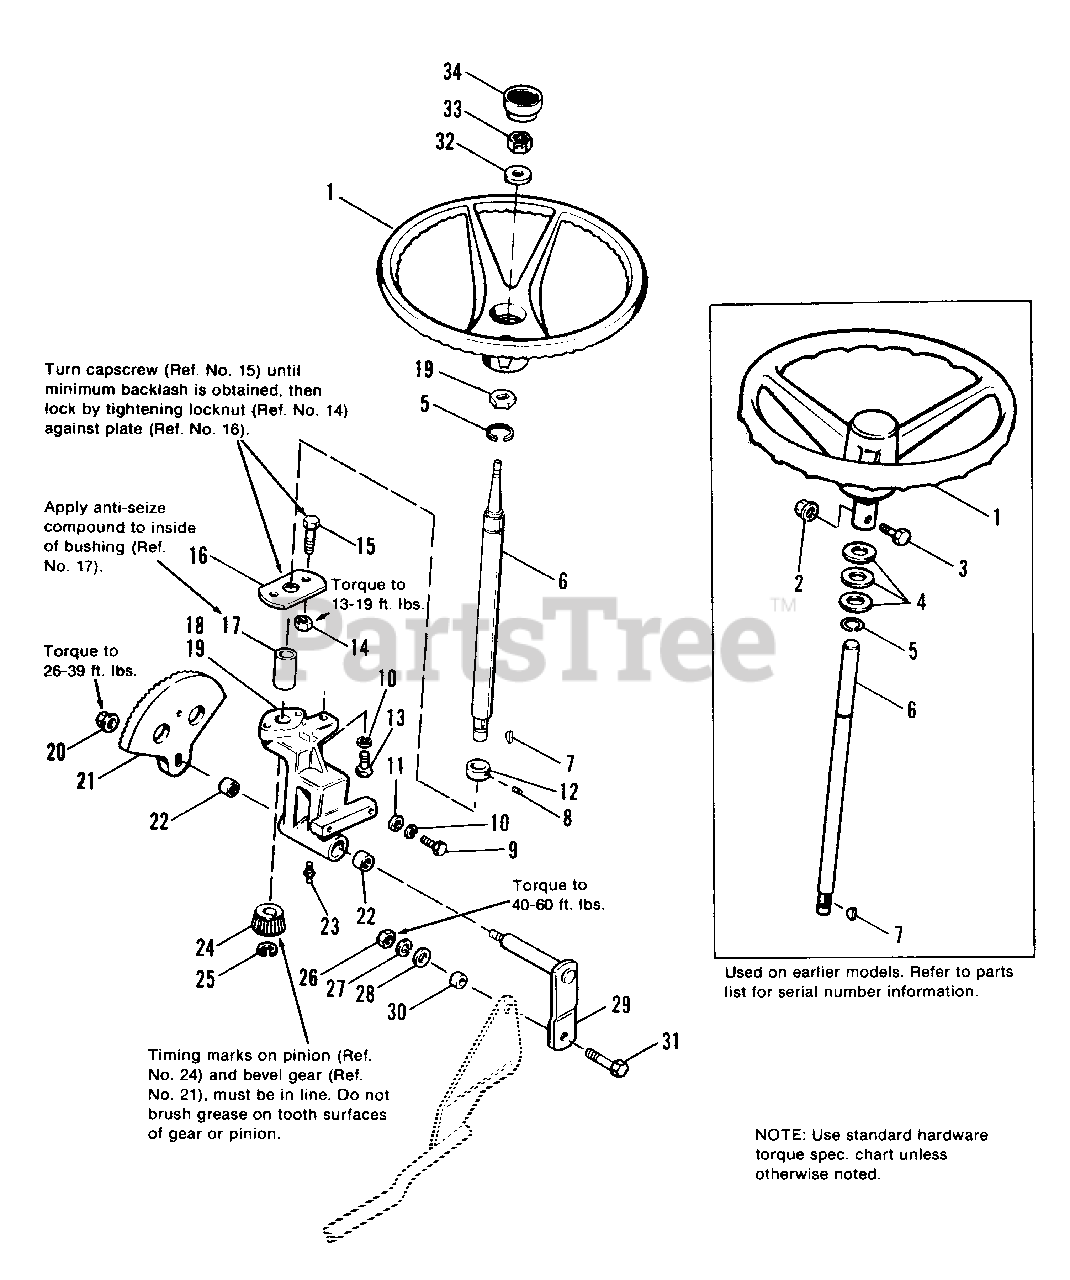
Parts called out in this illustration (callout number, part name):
1	WHEEL, Steering
2	LOCKNUT, Hex, Flange, 5/16-18
3	CAPSCREW, Hex Hd., 5/16-18 x 1-1/4
4	WASHER
5	RING, Retaining
6	SHAFT, Steering
7	KEY, Woodruff, #6
8	SETSCREW, 5/16-18 x 1/4
9	CAPSCREW, Hex Hd., 3/8-16 x 7/8
10	LOCKWASHER, 3/8
11	WASHER, Plain, 3/8
12	COLLAR, Set
13	CAPSCREW, Hex Hd., 3/8-16 x 3/4
14	LOCKNUT, Hex, Jam, 3/8-16
15	CAPSCREW, Hex Hd., 3/8-16 x 1-1/4
16	PLATE, Steering
18	HOUSING ASSY., Steering (Incl. Ref. Nos. 17 & 22)(Used with Steering Shaft 1667691)
18	HOUSING ASSY., Steering (Incl. Ref. Nos. 17 & 22)(Used with Steering Shaft 171020)
19	WASHER, Hex
20	LOCKNUT, Hex, Flange, 7/16-14
21	GEAR, Bevel
22	BEARING, Needle
23	FITTING, Grease
24	PINION, Bevel
25	E-RING
26	NUT, Hex, Full, 1/2-13
27	LOCKWASHER, 1/2
28	WASHER, Plain, 1/2
29	ARM ASSY., Steering
31	CAPSCREW, Hex Hd., 1/2-13 x 1-1/2
32	WASHER, Compression
33	LOCKNUT, Hex, Cntr., 5/16-18
34	CAP, Steering Wheel
